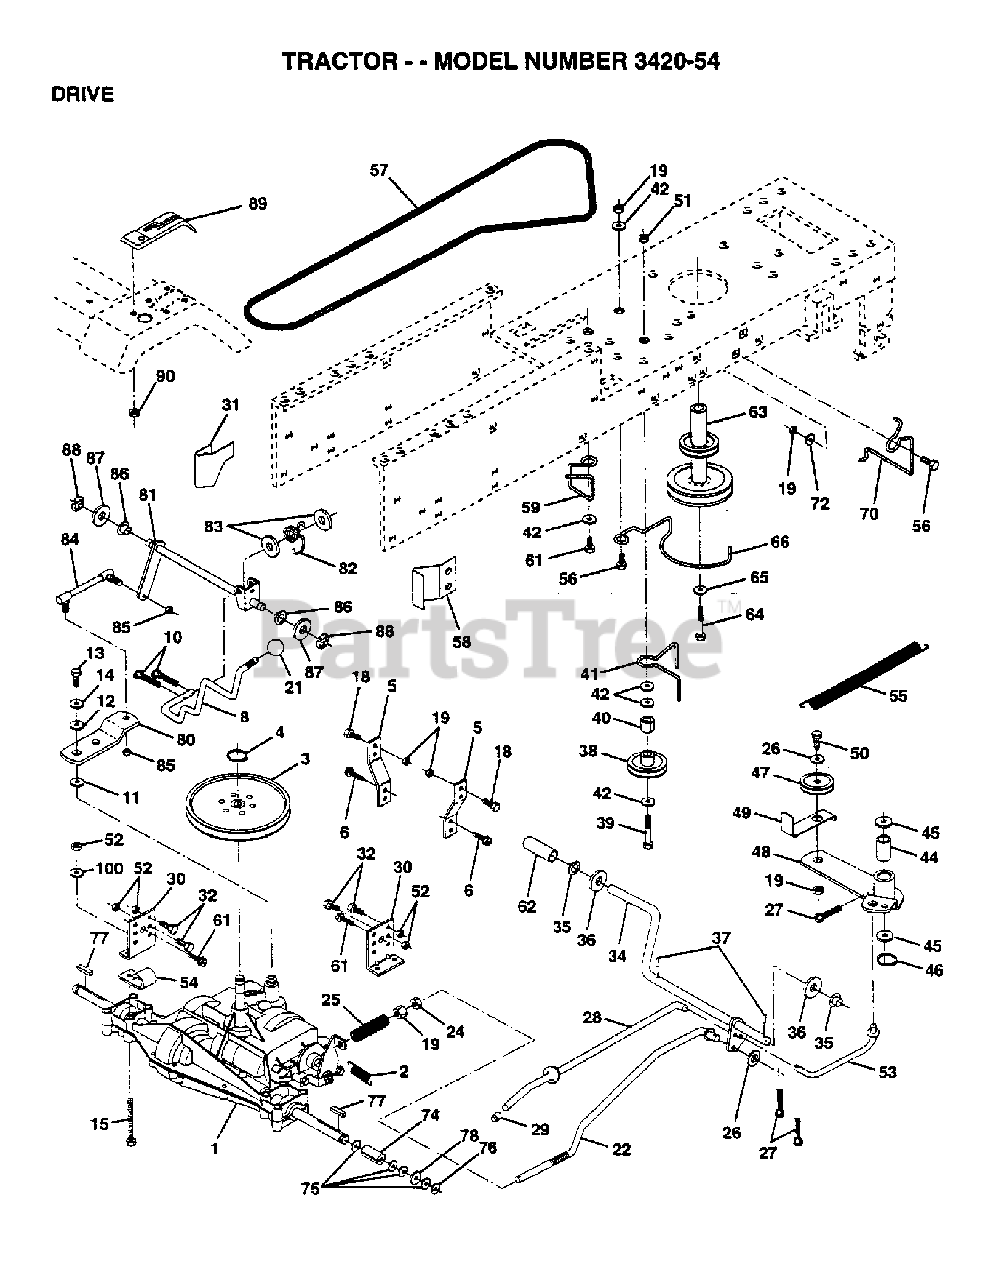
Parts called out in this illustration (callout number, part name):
1	TRANSAXLE ASSY 6 SPD
2	SPRING T
3	PULLEY TRANS
4	RETAINING RING LT
5	STRAP TORQUE
6	Screw, Lt
8	ROD SHIFT
10	PIN COTTER
11	WASH-SHFT PLT LT
12	WASHER
14	LOCKWASHER
15	BOLT HEX
19	NUT
21	KNOB T (1/2-HOLE)
22	ROD BRAKE
24	NUT
25	SPRING ROD LT
27	COTTER PIN
29	PLUNGER CAP
30	BRACKET TRANSAXLE
31	KEEPER BELT LH
32	BOLT
35	BEARING.NYLON
36	WASHER LT
37	Drive Pin, 3/16 X 1"
38	FLAT IDLER PULLEY
40	SPACER T
41	BELT KEEPER LT
42	WASHER
44	BEARING LT (2 2)
45	WASHER LT
46	KLIP RING
47	Idler Pulley
49	RETAIN BELT
50	Hex Bolt
51	LOCKNUT
52	LOCKNUT
54	CLIP T
55	SPRING, RETURN LT
57	Ground Drive Belt, 95.25
62	PEDAL COVER
63	PULLEY ENGINE
65	LOCKWASHER
66	KEEPER, BELT
70	KEEPER BELT ENG
72	WASHER
74	SPACER LT
76	E-RING LT
77	SQUARE KEY
80	SHIFT ARM
82	SPRING,TORSION
83	WASHER
85	NUT 1/4-28
86	BUSHING.STEERING.ROD
87	WASHER D
88	KLIP RING
90	NUT.PUSH.3/16
100	WASHER M
